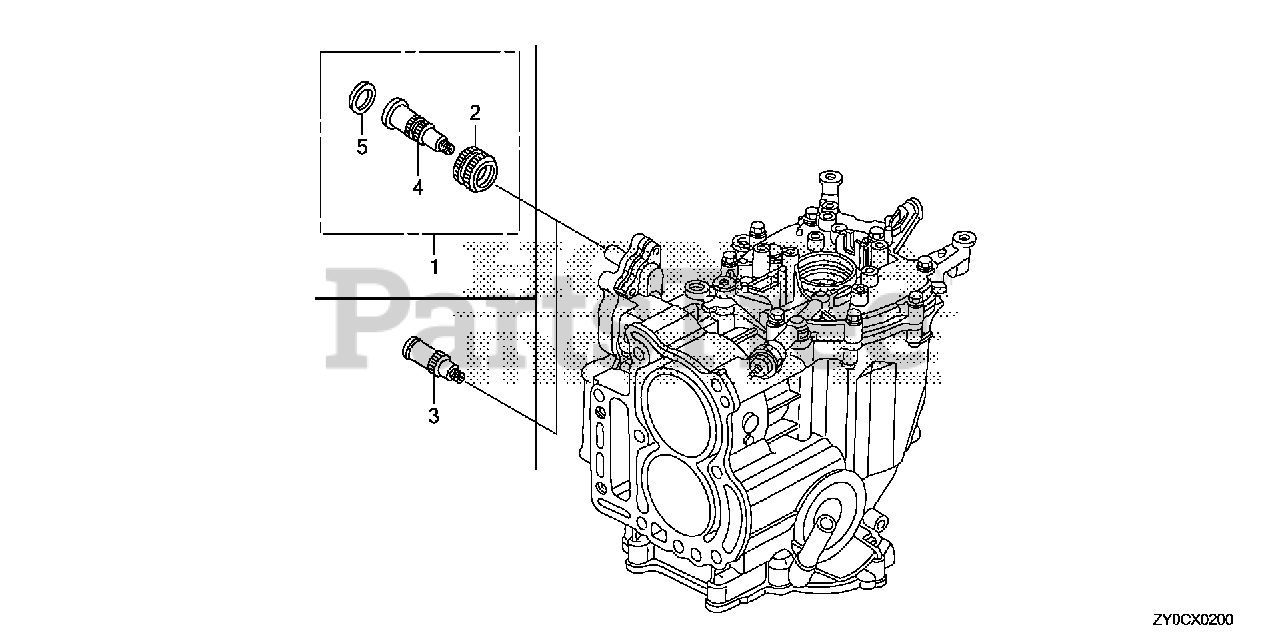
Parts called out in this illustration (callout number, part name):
1	JOINT KIT, WATER HOSE
2	NUT, WATER MOUTH Use from Frame SN 1000929.
3	JOINT, WATER HOSE
4	JOINT, WATER HOSE
5	SEAT, WATER MOUTH Use from Frame SN 1000929.
